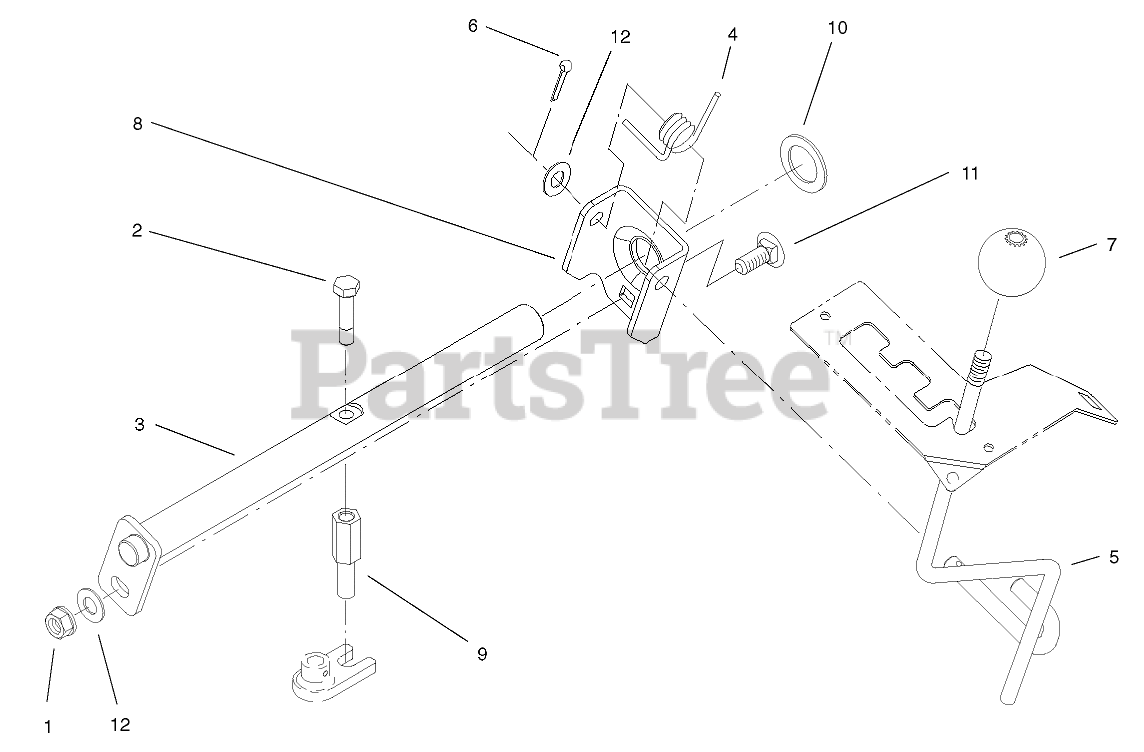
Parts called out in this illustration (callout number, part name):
1	NUT-LOCK, NI
2	SCREW-THREAD LOCKING
3	SHIFT ROD ASM
4	SPRING-TORSION
5	LEVER-SHIFT
6	PIN-COTTER
7	KNOB-HI / LO SHIFT
8	BRACKET-PIVOT
9	ROD-PIVOT, SHIFT
10	SPACER
11	SCREW-CARR
12	WASHER-FLAT
